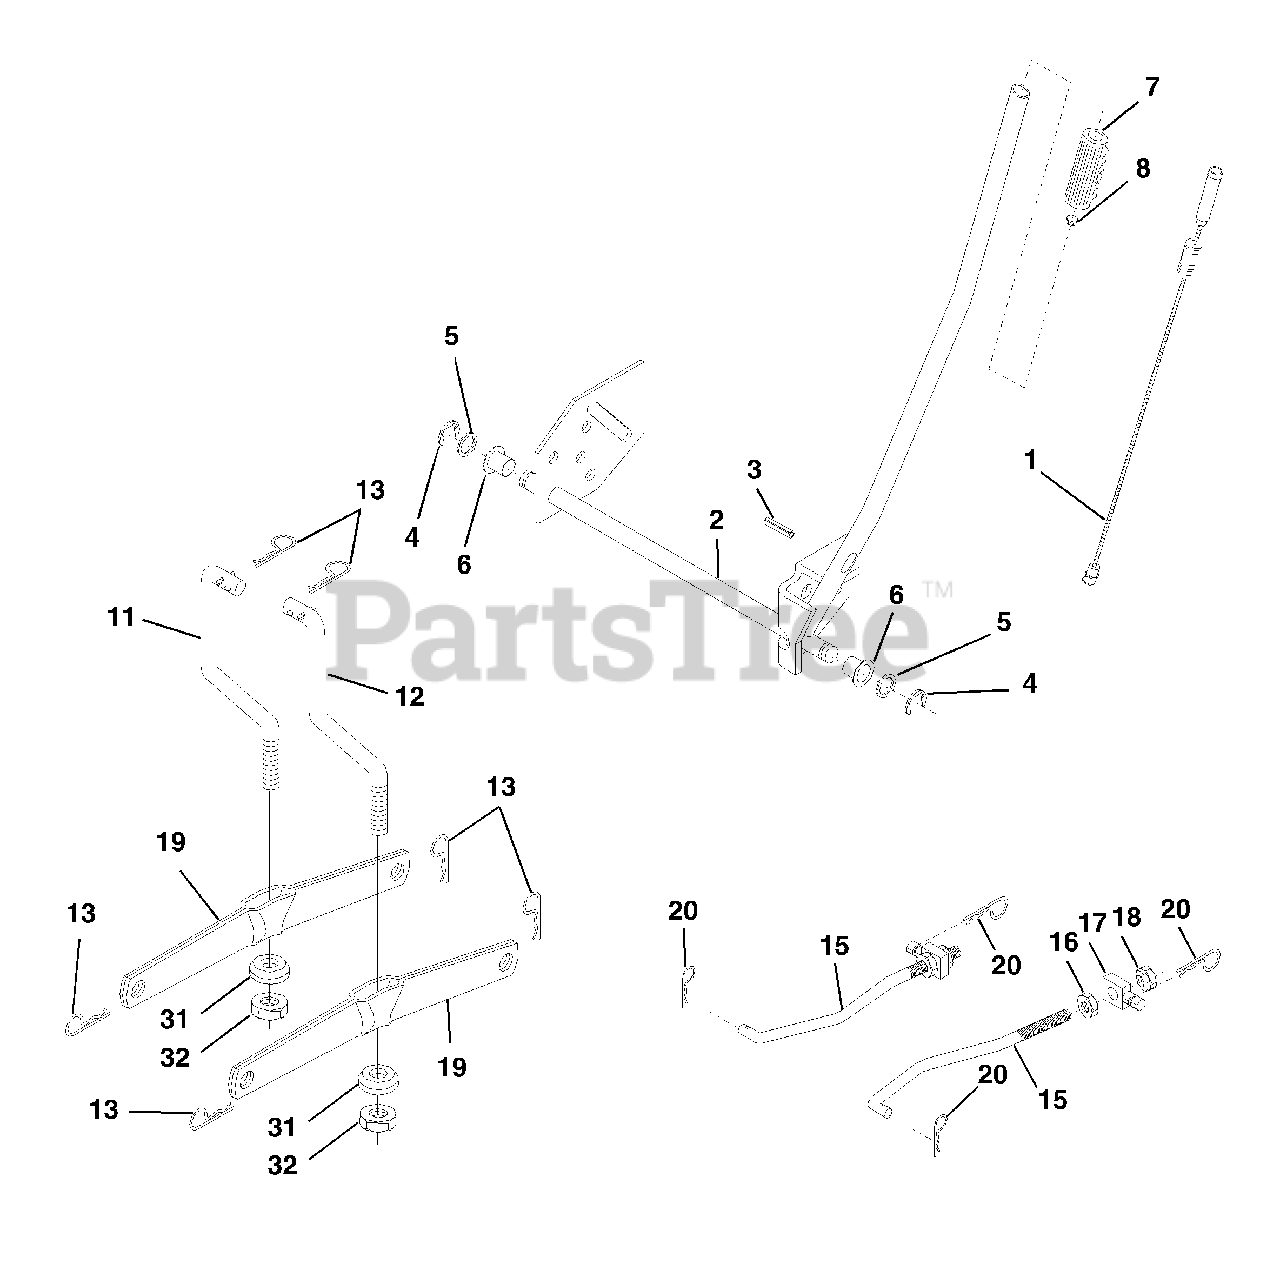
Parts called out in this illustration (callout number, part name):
1	Wire Asm Inner W/plunger
2	Shaft Asm Lift
3	Pin Groove
4	E Ring #5133-62
5	Washer PLTD 21/32 X 1 X 21ga
6	Bearing Nylon Blk 629 Id
7	Grip Handle Bicycle
8	Button Plunger Black
11	Link Lift LH
12	Link Lift RH
13	Retainer Spring
15	Link Front
16	Nut Jam Hex 1/2-13 Unc
17	Trunnion Blk Zinc
18	Nut Crownlock 1/2-13 Unc
19	Arm Suspension Rear
20	Spring, Retainer
31	Bearing Pvt. Lift Spherical
32	Nut Crownlock 3/8-24
